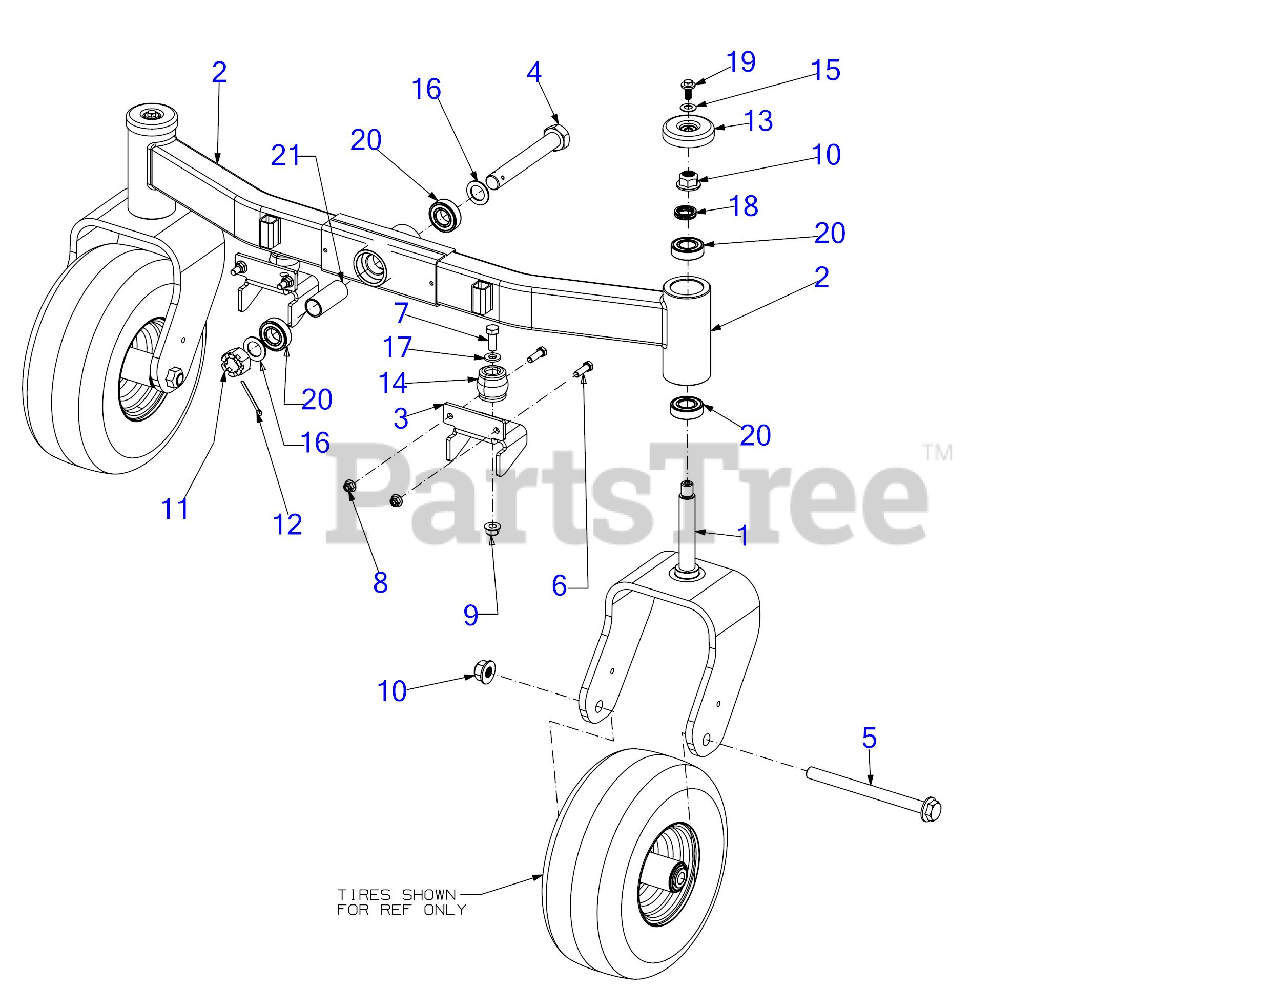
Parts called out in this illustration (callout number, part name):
4	HEX HEAD SCREW 1-14 X 7 GR5
5	SCREW 3/4-16 x 9.00 GR5
6	SCREW 3/8-16 x 1.25 GR5
7	SCREW 1/2-13 x 1.25 GR5
10	FLANGE LOCK NUT 3/4-16 TOP LOCK
11	CASTLE NUT 1.0-14 GR5
12	COTTER PIN
13	AXLE CAP 3"
14	AXIAL BUMPER
15	BELL WASHER
16	FLAT WASHER 1.031 X1.62 X.095
17	FLAT WASHER .510 x 1.000 x .125
18	WAVE WASHER
20	BALL BEARING 1.0 X 52 X 15
21	SPACER 1.00 X 1.25 X 2.99
